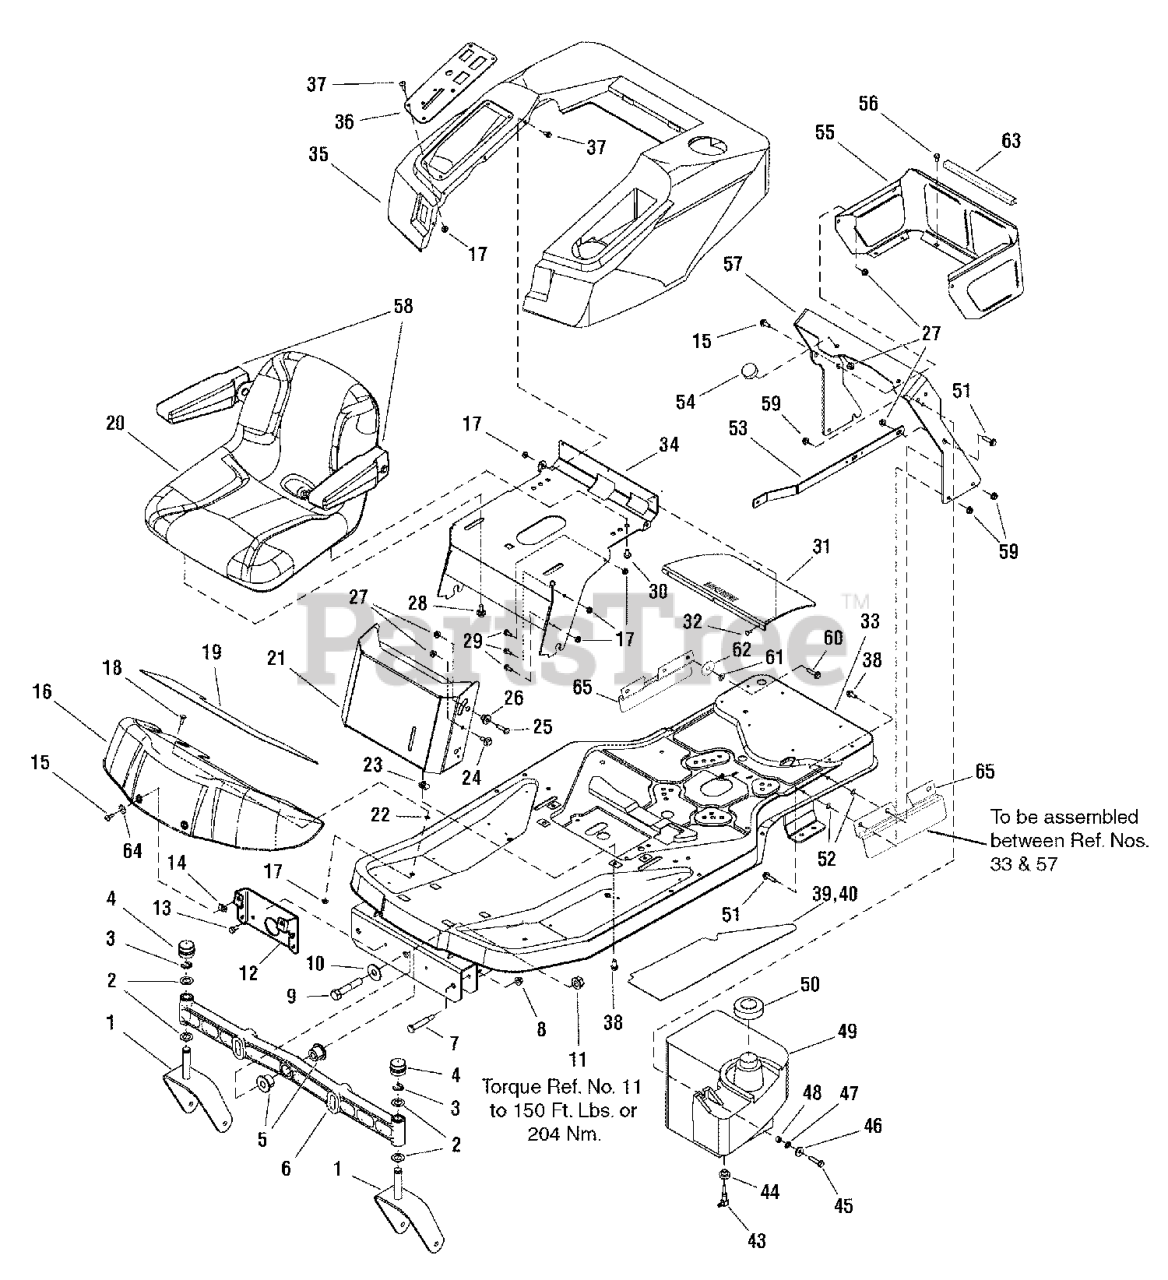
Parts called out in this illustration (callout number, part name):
1	CASTER ASSEMBLY
2	WASHER, 0.750 ID x 1.60 OD x .05 Thick
3	RING, Klipring, For 3/4 Dia. Shaft
5	BUSHING, Axle Pivot
6	AXLE, Casting
7	BOLT, Shoulder, G5
8	NUT, Hex Flange Nylock, ESNA, 3/8-16
9	CAPSCREW, Hex Head, 5/8-11 x 3 1/4
10	WASHER, 5/8
11	NUT, Hex Flange, 5/8-11
12	BRACKET, Front Footrest Support
13	CAPSCREW, Hex Washer Head, Taptite, 5/16-18 x 5/8
14	NUT, Speed Lug Type, 1/4-20
15	SCREW, Truss Head, Torx Drive, 1/4-20 x 3/4
16	PANEL, Footrest, 18 Ga ZT 7000, Red
17	NUT, Hex Flange, , ESNA, 1/4-20
18	BOLT, Carriage, Short Neck, 1/4-20 x 3/4, G5
19	PAD, Footrest Panel
20	SEAT ASSEMBLY, with Armrests
21	PANEL, Front with Slot
21	PANEL, Front Manual Brake and Deck Lift
22	PUSHNUT, 1/4 x 1/2 OD
23	NUT, Speed, Lug Type, 5/16-18
24	BOLT, Shoulder, 5/16-18 x 1/4
25	BOLT, Carriage, 5/16-18 x 1 1/4
26	PIVOT, Hood, Powdered Metal
27	NUT, Hex Flange Whiz Lock Small, 5/16-18
28	BOLT, 5/16-18 X .75, .50 Shoulder G5 YEL
29	SCREW, 1/4-20 x 3/4" Hex Whiz Lock Flange
30	SCREW, 5/16-18X0.750, GR5, WHIZ-LOCK, ZC
31	SCREEN, Top, Seat Deck
31	SCREEN, Seat Deck
32	RIVET, Pop
33	FRAME ASSEMBLY
34	SUPPORT, Seat
35	SEAT DECK, Red Poly, ZTS - Red
36	PLATE, Control, ZTS - Black
37	SCREW, Truss Head, Torx Drive, 1/4-20 x 3/4
38	CAPSCREW, Hex Head, Flange Whiz Lock, 5/16-18 x 3/4
39	PAD, Footrest R.H.
40	PAD, Footrest L.H.
43	ELBOW, Gas Tank
44	BUSHING
45	CAPSCREW, Hex Head, 5/16-18 x 1-1/2, G5
46	WASHER, Flat, .34 ID x 1" OD
47	WASHER, 5/16" Internal/External Tooth Lock
48	SPACER, .316 I.D. x .375 O.D. x .310 thick
49	TANK, Fuel
50	CAP, Fuel Tank, vented (Used on clear tank)
51	CAPSCREW, Hex Head, 5/16-18 x 1 1/4
52	NUT, Push Pal, 5/16 DIA Thread, 5/8 OD
53	STRAP, Fuel Tank Brace
54	BUMPER, Rubber
55	SHROUD, Rear
56	CAPSCREW, Hex Washer Head, Taptite, 1/4-20 x 1/2
57	SUPPORT, Seat Deck
58	ARM REST KIT, L.H. & R.H.
59	NUT, Hex Flange Nylock, 5/16-18
60	CAPSCREW, Hex-Head, 3/8-16 X 1-1/4, G5
61	NUT, Push Pal, 3/8
62	WASHER, 3/8 (0.41 ID X 1.5 OD X .25 Thick) Black
64	WASHER, 5/16" External Tooth Lock Washer, Yellow
65	GUARD, Debris
